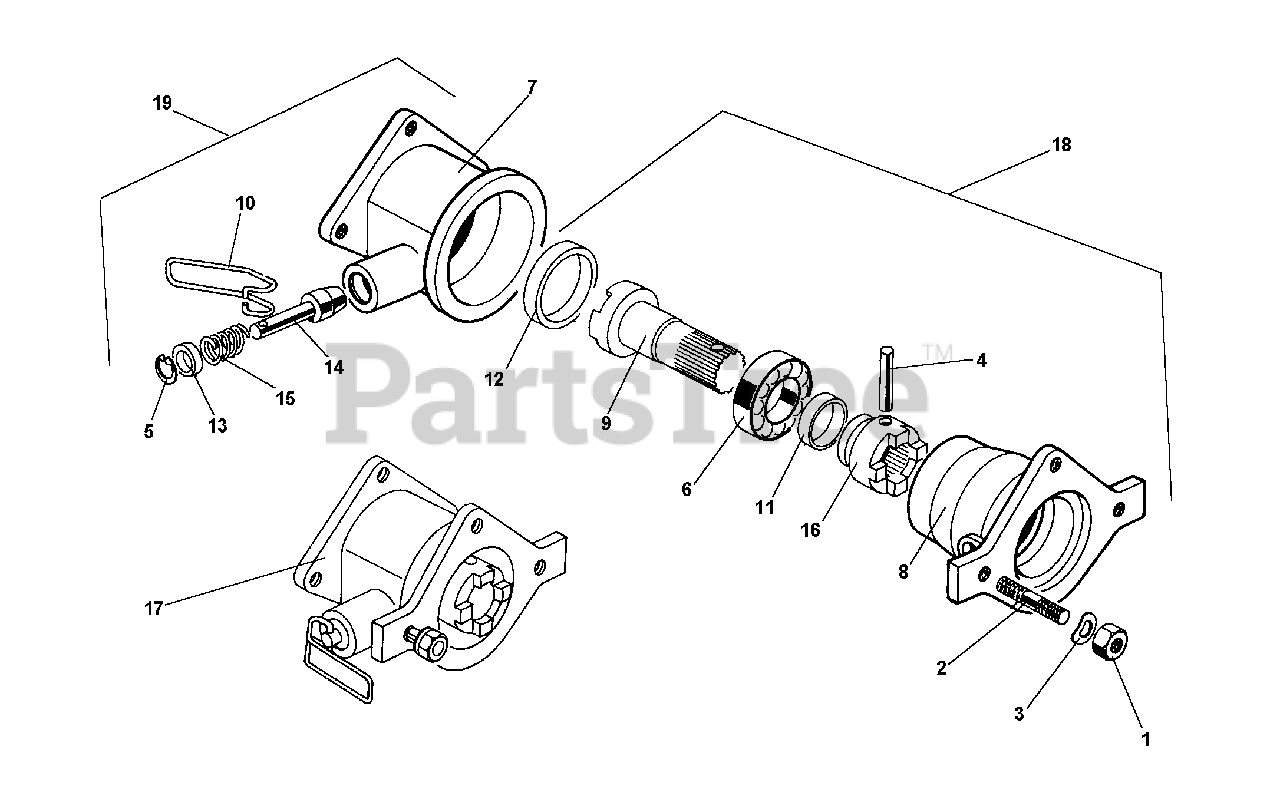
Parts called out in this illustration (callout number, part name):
1	NUT, M12 X 1.25
2	STUD M12 X 1.25 X 40 X 11 X 25
3	WASHER, LOCK 13
4	LOCKING PIN 6 X 40
5	CIRCLIP, INTERNAL
6	BEARING 25 X 47 X 12
7	BUSHING FOR QUICK HITCH
8	TANG FOR QUICK HITCH
11	RING FOR HALF AXLE
12	EXTENSION RING
15	PUSH ROD SPRING
17	QUICK HITCH ASSEMBLY
18	TANG ASSEMBLY
19	BUSHING ASSEMBLY
